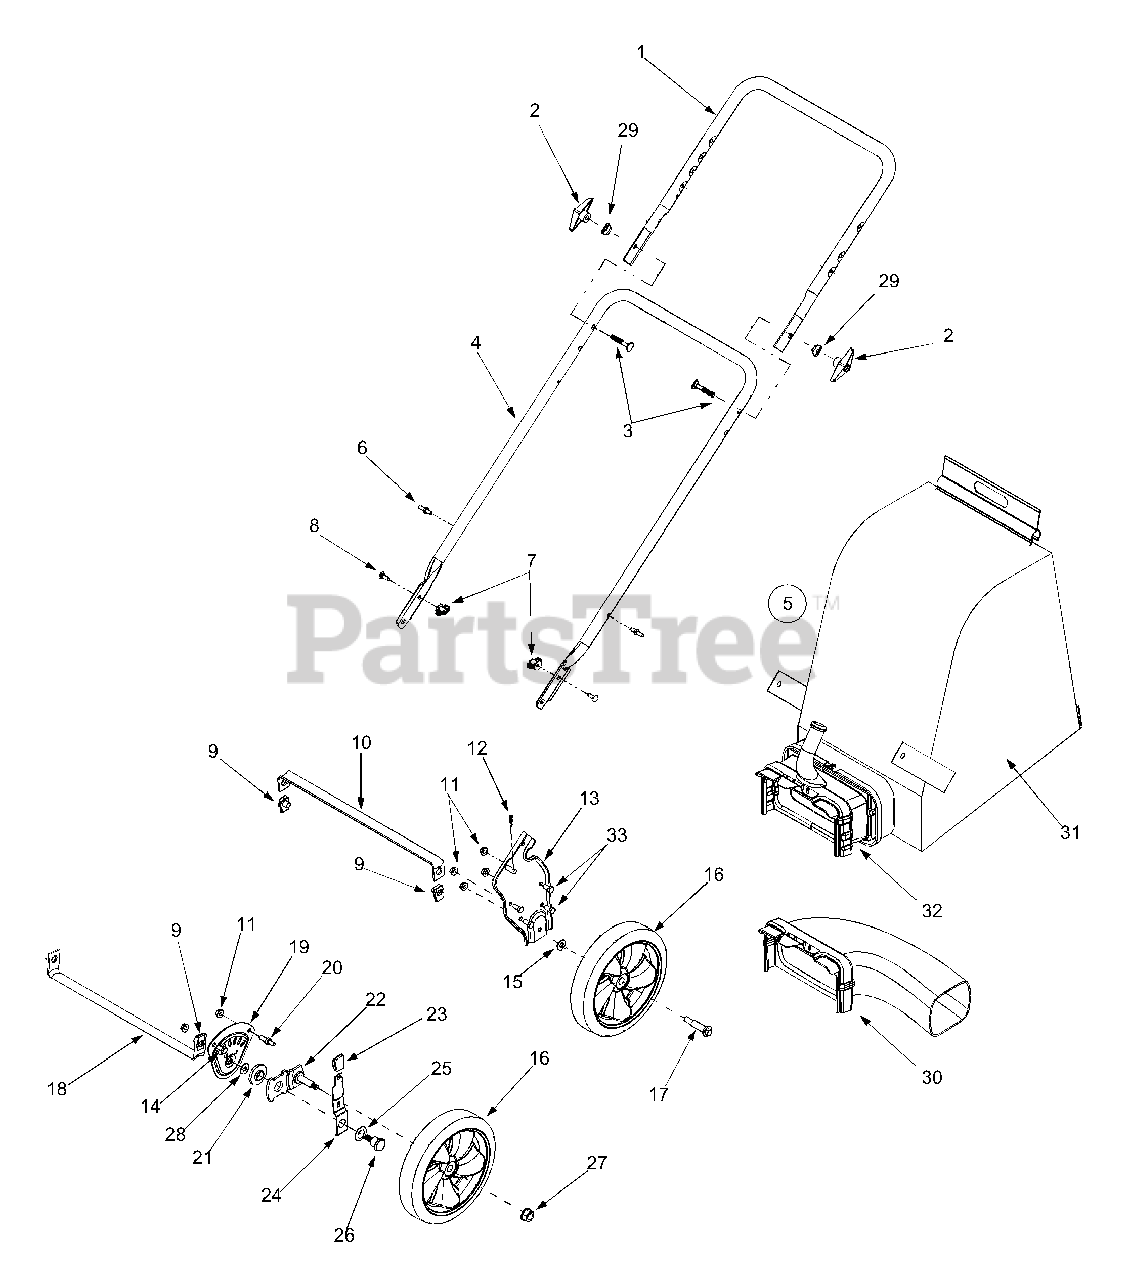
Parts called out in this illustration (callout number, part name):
3	Carriage Bolt
5	Bag Assembly
6	Studs
7	Wing Nut 1/4-20
8	Carriage Screw 1/4-20 x.75
9	Lock U-Clip Nut 3/8-16
12	Cotter Pin
14	Hex Cap Screw 5/16-18 x.625
15	Bell Washer.401 ID x.870 OD
16	Wheel 8 x 8.1
17	Shoulder Screw 3/8-16
21	Height Adjustment Bearing
22	Pivot Arm Assembly
23	Height Adjustment Knob
24	Spring Lever
25	Bell Washer .760 ID x .25OD
26	Shoulder Screw .750 ID x .625 OD
27	Flange Lock Nut 3/8-16
28	Thrust Washer .375 ID x .70 OD
29	Saddle Washer
30	Blower Chute Ass'y (if so equipped)
31	Bag
32	Chute Assembly
33	Hex Cap Screw 5/16-18 x.750
